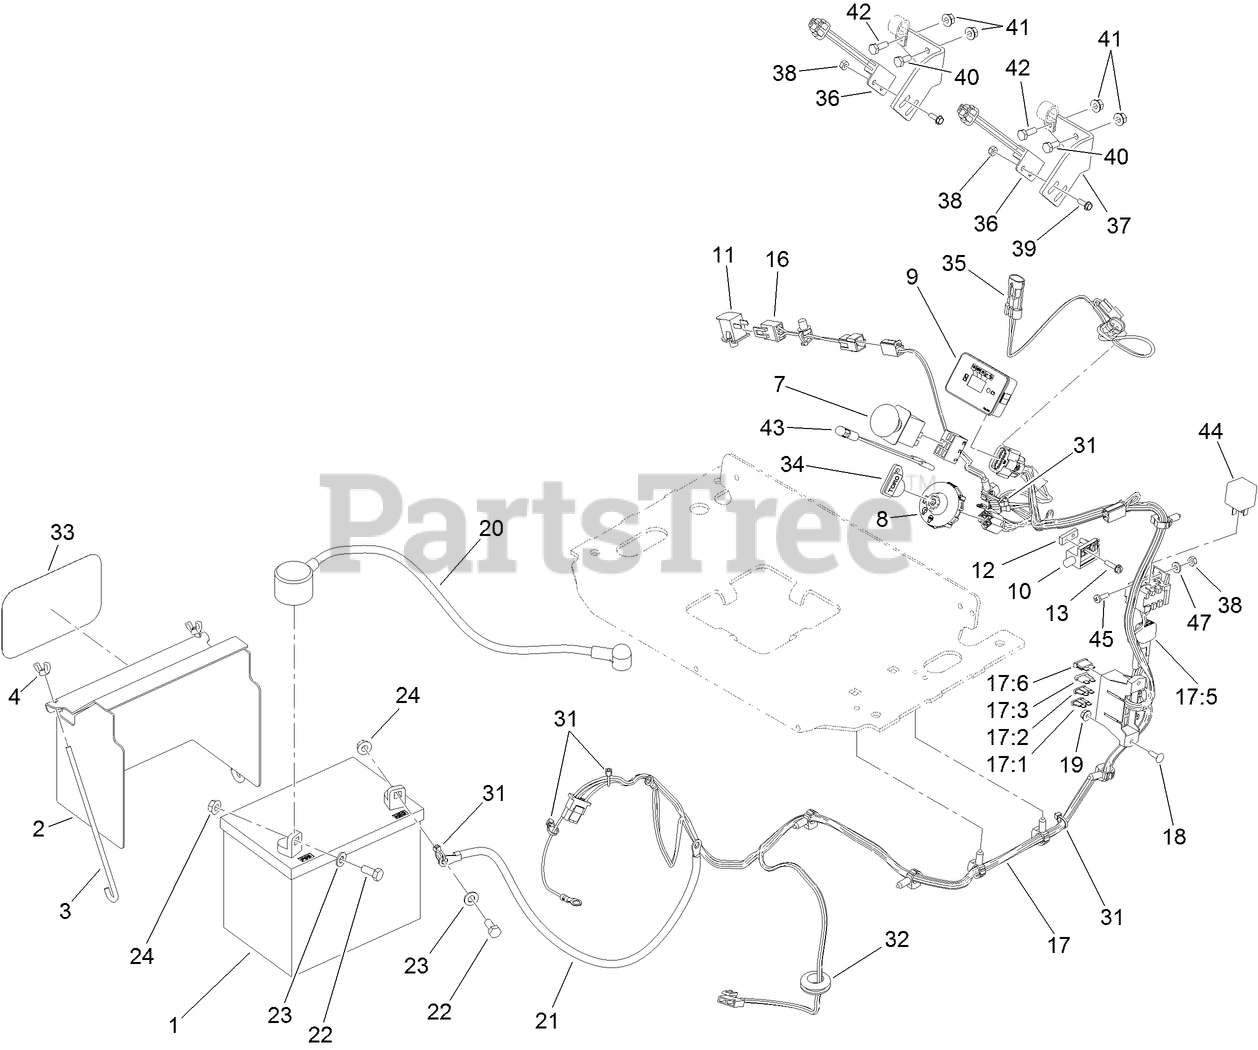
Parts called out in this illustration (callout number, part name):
1	BATTERY-DRY
2	COVER-BATTERY
3	BOLT-HOLDDOWN
4	WINGNUT
7	SWITCH-PTO, ON-ON-(ON)
8	SWITCH-IGNITION
9	MODULE-HOUR METER
10	SWITCH-CLOSED, NORMALLY
11	SWITCH-BAIL
12	PLATE-TAPPED
13	SCREW-HWH
16	HARNESS-WIRE, JUMPER (OPC)
17	Harness-Wire, EFI
17:1	FUSE-BLADE, 30 AMP
17:2	FUSE-BLADE, 25 AMP
17:3	FUSE-BLADE, 10 AMP
17:6	FUSE-BLADE, 15 AMP
18	BOLT-CARR
19	NUT-HF
20	CABLE-BATTERY, POSITIVE
21	CABLE-BATTERY, BLACK
22	SCREW-HH
23	WASHER-PLAIN
24	NUT-HHF, SMOOTH
31	TIE-CABLE
32	GROMMET
33	DECAL
34	KEY-IGNITION
35	HARNESS-WIRE, NEUTRAL SWITCH
36	SWITCH-PROXIMITY
37	BRACKET-MOUNT, SWITCH
38	NUT-LOCK, NI
40	SCREW-HH
41	NUT-HHF
42	SCREW-HH
43	INDICATOR-LED, RED
45	SCREW-PPH
47	WASHER-FLAT
